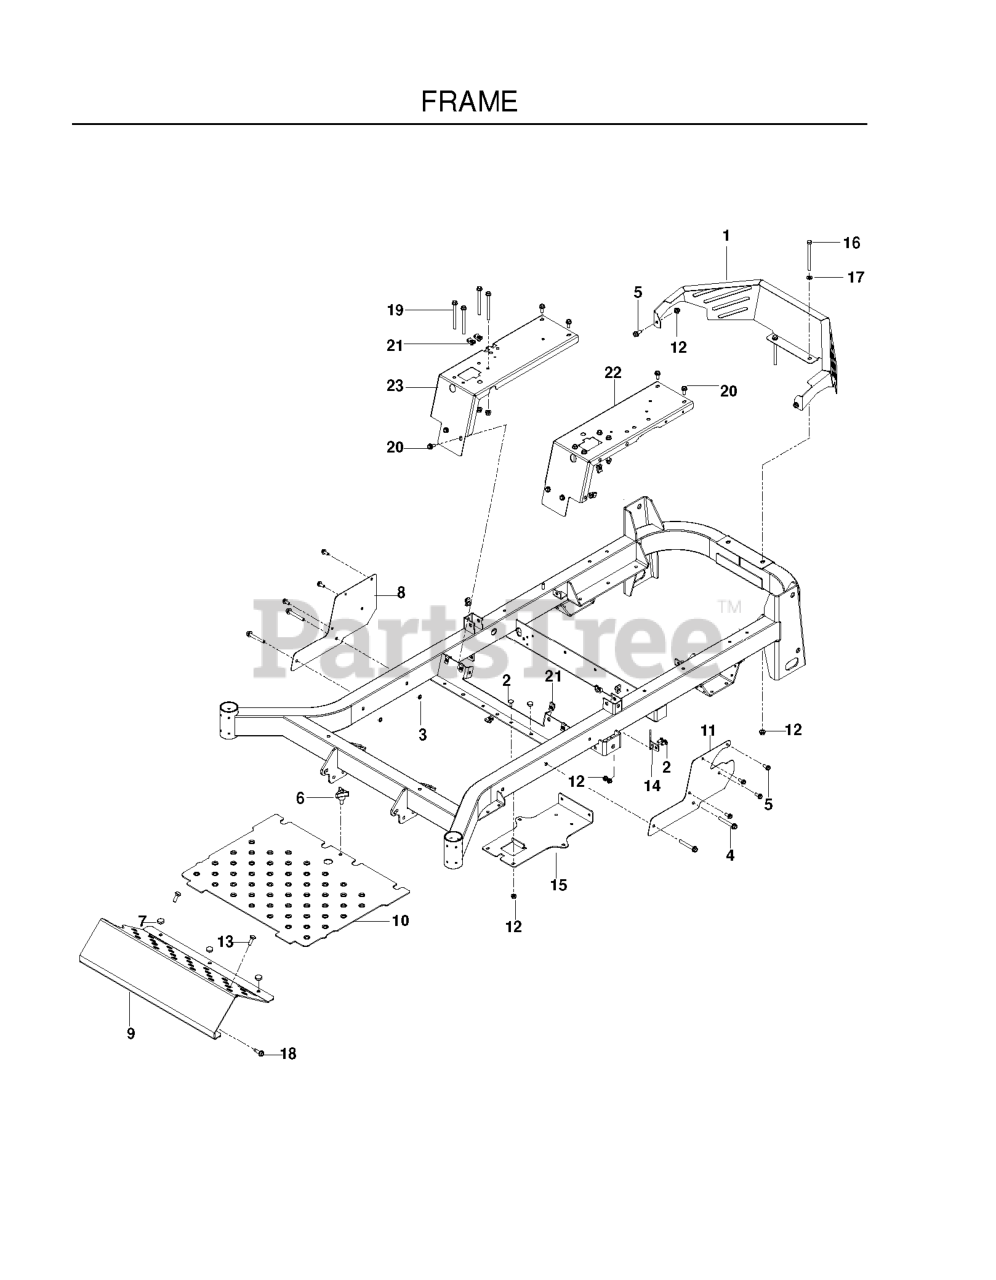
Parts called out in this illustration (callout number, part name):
1	GUARD.REAR.ULTRA.BLUE.DIXON
2	BOLT 5/16C X 3/4" CARRIAGE
3	NUT HEX 3/8-16 NYLON, THIN
4	HHFS 3/8-16 X 2 3/4
5	HHFS 5/16-18 X 3/4
6	KNOB W/STUD
7	GROMMET, BUMPER
8	SIDE, RT, BL
9	PLATE.FOOTREST.RAM.DARK.BLUE
10	FLOOR PAN W/DECALS
11	SIDE, LT, BL
12	5/16-18 NYLOC FLANGE NUT
13	RHSNB 5/16C X 1
14	STOP, DECK, EZ+
15	PLATE, BATTERY, BLACK
16	HCS 5/16C X 4
17	FLAT WASHER 5/16 SAE
18	RP BLT 5/16-18 X 1 THRD FORM D
19	HHFS 5/16-18 X 3 3/4
20	HHFS 5/16-18 X 3/4
21	U-CLIP 5/16-18 NUT RETAINER
22	PANEL, FILLER LT, BLUE
23	PANEL.FILLER.RT.DIXON.BLUE
